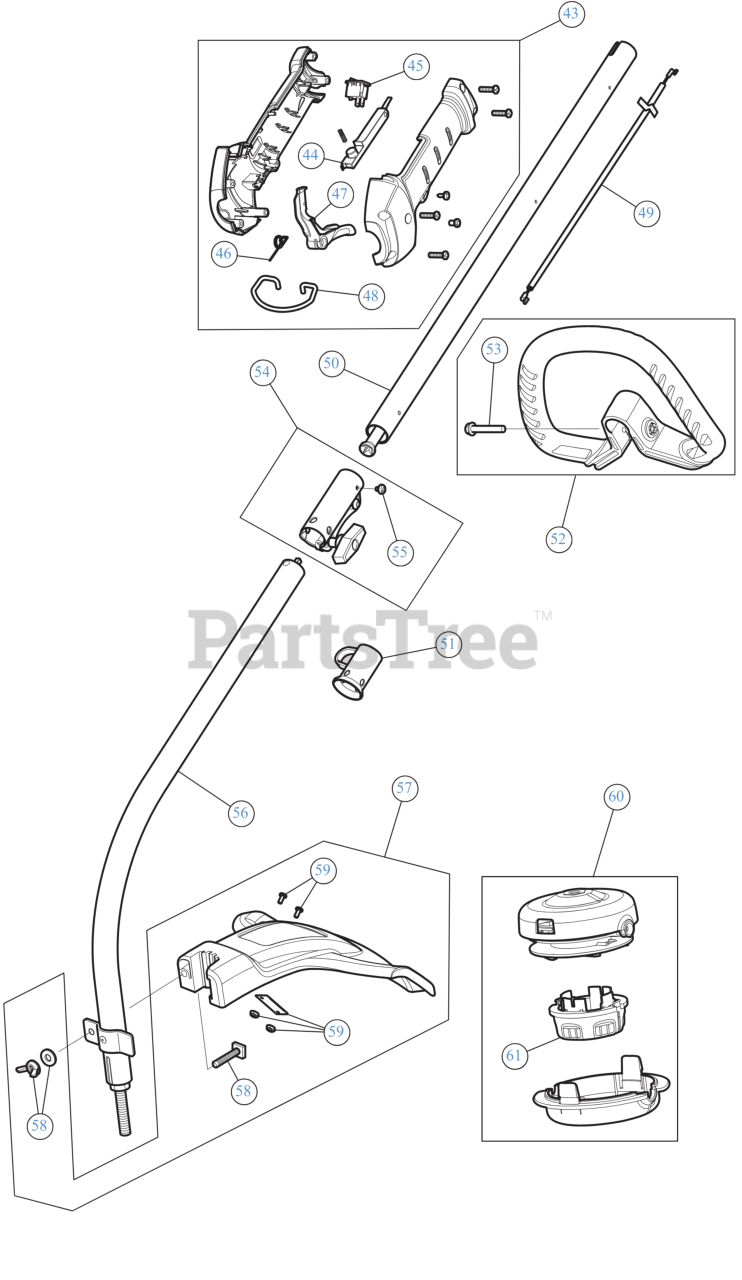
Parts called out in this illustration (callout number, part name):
43	THROTTLE GRIP ASM
44	LEVER LOCK OUT
45	SW, MOMENTARY ON/O
46	SPRING TRIG
47	THROTTLE TRIGGER
48	SHOULDER STRAP CLIP
49	THROTTLE CABLE
52	HANDLE ASSEMBLY
53	BOLT 1/4-20X1 1/2
54	SPLIT BOOM COUPLER KIT
55	SCREW, 10-32X.250 TA
56	LOWER BOOM
57	GUARD ASSEMBLY
58	BLADE GUARD MOUNTING HARDWARE
59	ASSEMBLY, BLADE
60	CUTTING HEAD ASSEMBLY
